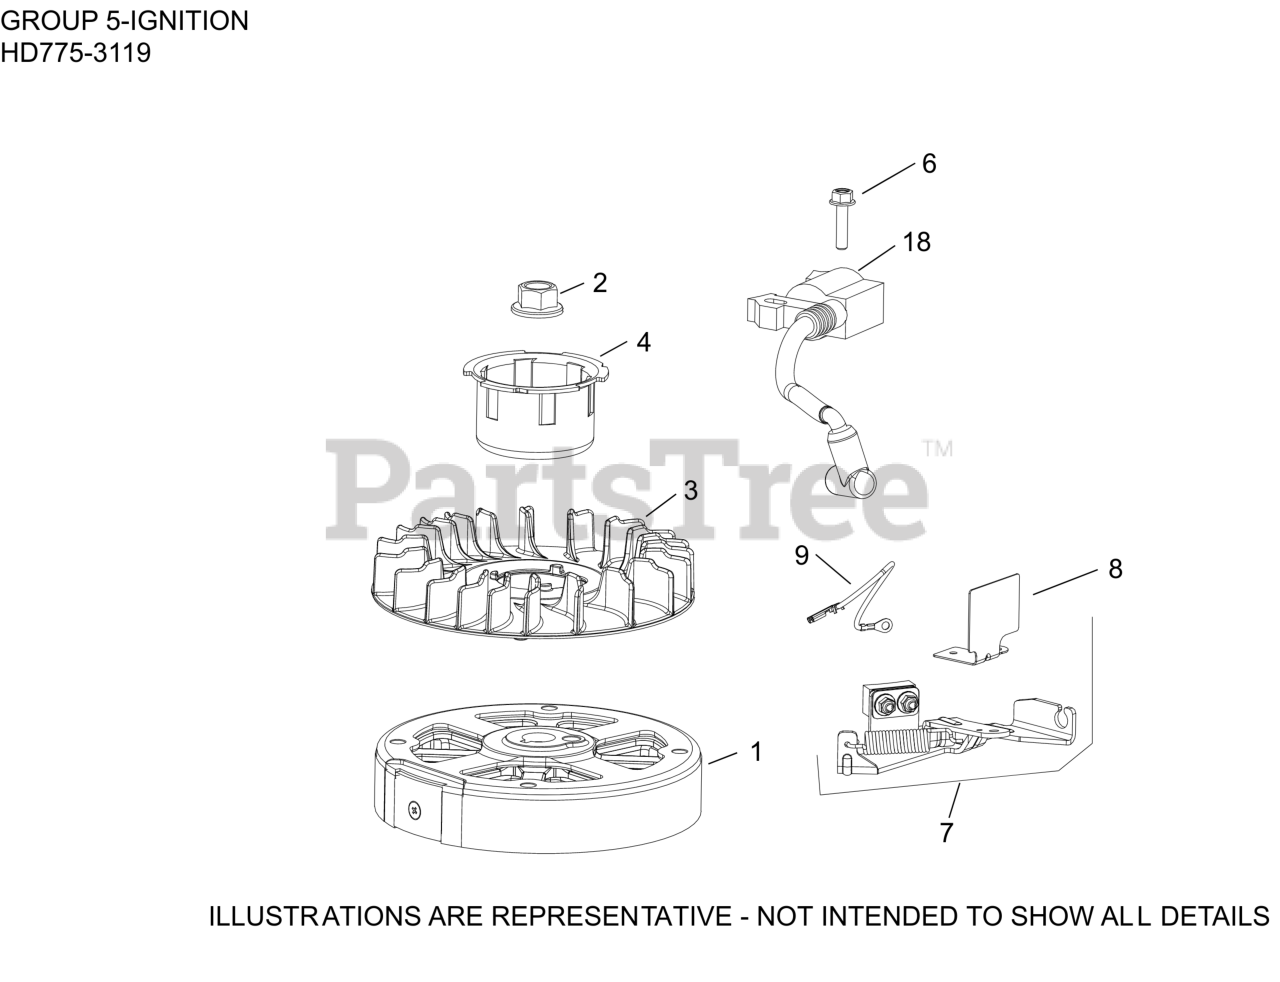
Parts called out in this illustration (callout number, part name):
1	FLYWHEEL ASSEMBLY
2	NUT, FLYWHEEL (W/SERRATIONS)
3	FAN, FLYWHEEL
4	CUP, DRIVE - (#1410905S)
6	SCREW, M6 X 25-(#25086436S)
7	BRAKE ASSEMBLY
8	GUARD, BRAKE (FINGER PROTECTION)-DISC.
9	LEAD, KILL (BRAKE TO IGN MODULE)
18	MODULE IGNITION CAST IRON FLYWHEEL
